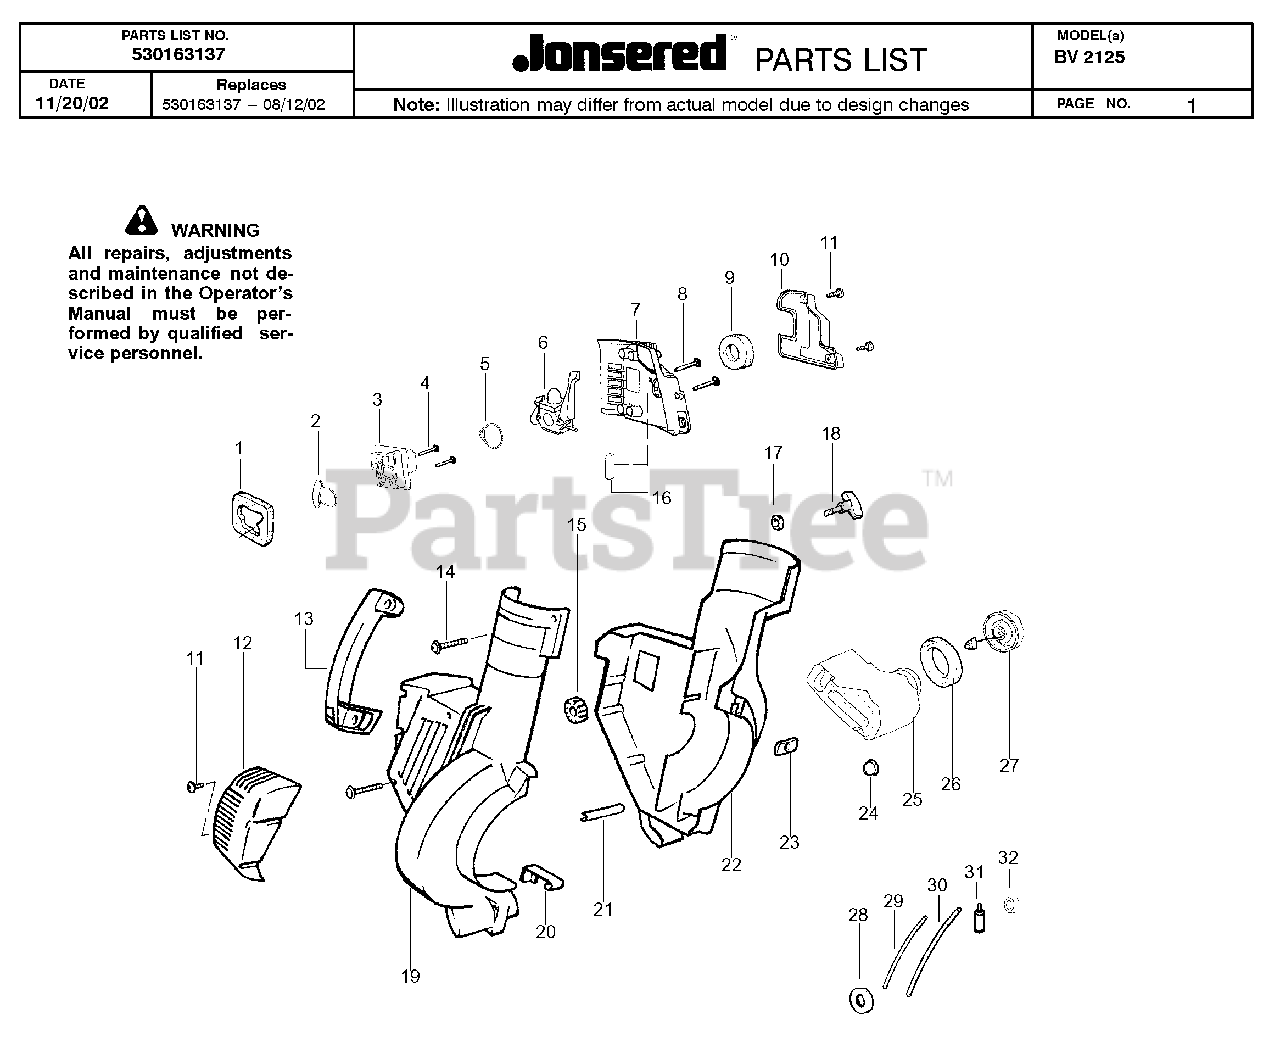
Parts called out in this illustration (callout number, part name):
2	GASKET KIT
5	GASKET KIT
11	SCREW FILTER PLATE
14	SCREW-10-14 X 13/16 (PL
24	CRANKCASE ISOLATOR
31	FUEL PICK-UP ASSY
530071632	CARB
